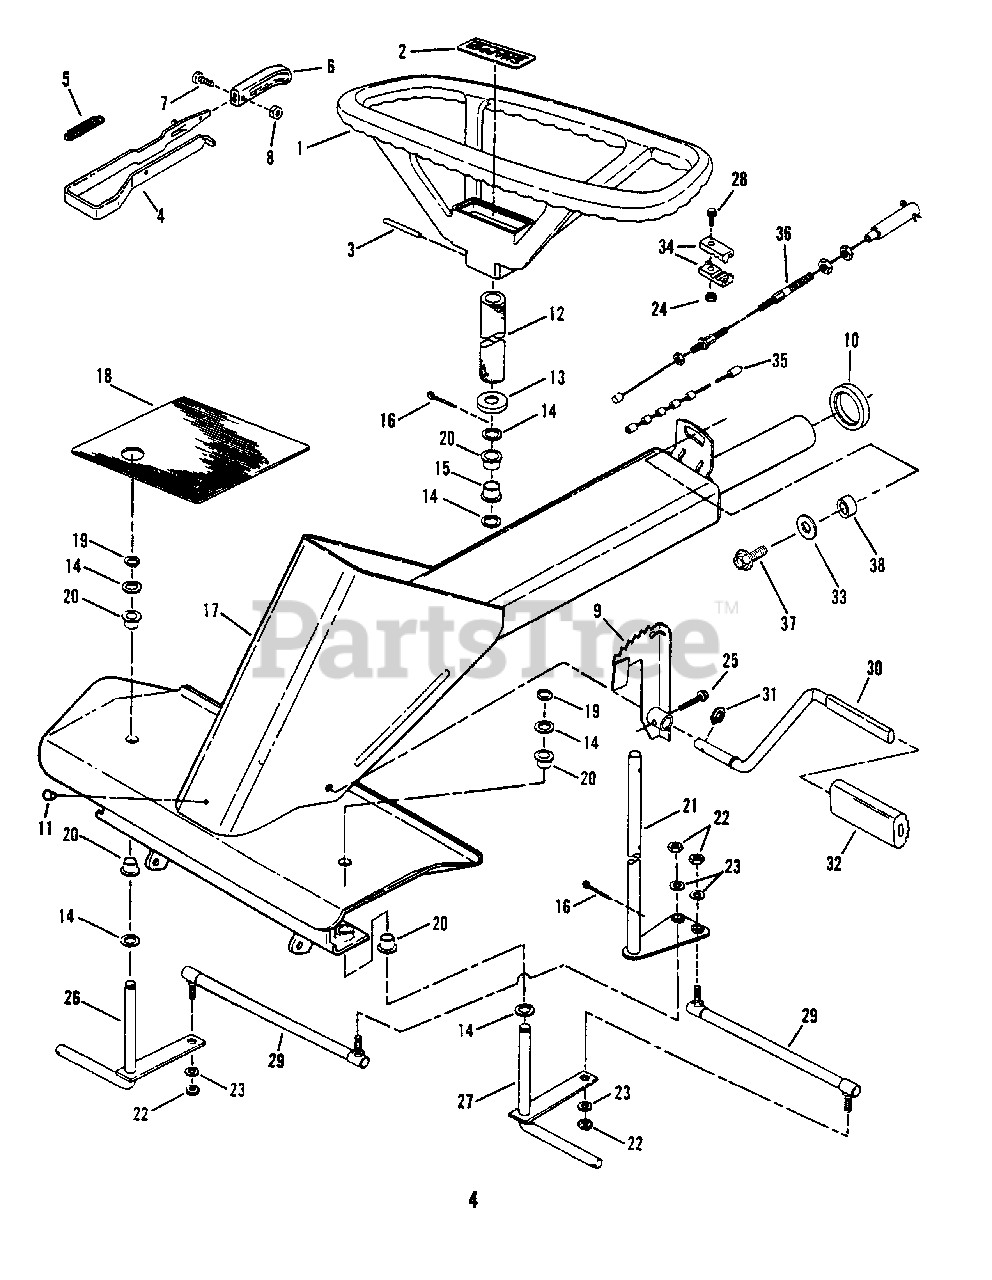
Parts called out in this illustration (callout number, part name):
1	ASSEMBLY, Steering Wheel
2	DECAL, Snapper
3	PIN, 1/4 x 1-1/2" Roll
4	BRACKET, Clutch/Brake
5	SPRING
6	KNOB
7	SCREW, #8-32 x 3/8" Cross Recess
8	NUT, #8-32 Hex
9	ARM, Clutch/Brake
10	SPACER, Main Tube
11	PLUG
12	COVER, Steering Shaft (Foam)
13	COVER
14	WASHER, 3/4 Flat
15	BUSHING, 3/4" Steering Shaft
16	PIN, 3/16 x 1-1/2" Cotter
17	FRAME, Front
18	PAD, Foot
19	RING, Retaining
20	BEARING
21	SHAFT, Steering (Wide Front End)
22	NUT, 5/16-24 Hex
23	WASHER, 5/16 Split Lock
24	NUT, 1/4-20 Hex Center Lock
25	SCREW, 5/16-18 x 1-1/4" Self-Tapping
26	PIN, Wide King (Right Side)
27	PIN, Wide King (Left Side)
28	SCREW, 1/4-20 x 3/4" Hex Head Cap, Grade 5
29	TIE-ROD (2) (42" Models)
30	PEDAL, Clutch/Brake
31	RING, 5/8" External Retaining
32	PAD, Clutch/Brake Pedal
33	WASHER, 3/8" Flat
34	UNION, Cable
35	CABLE, Clutch
36	CABLE, Brake
37	SCREW, 3/8-16 x 5/8" Self Tapping
38	SPACER 25/64 x 5/8 x 3/16"
